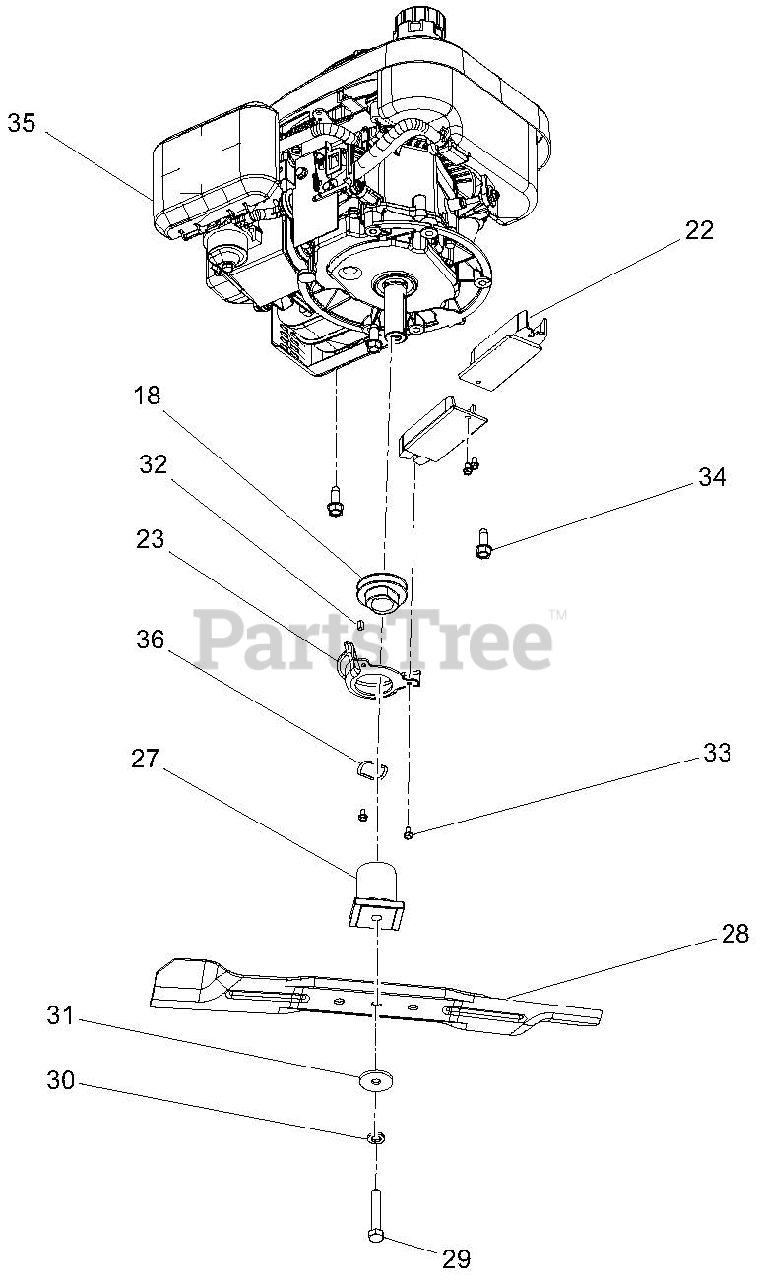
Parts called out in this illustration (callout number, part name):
18	PULLEY, GROUND DRIVE, LM
22	GUIDE, BELT INNER
23	GUIDE, BELT CRANK
27	ADAPTER, BLADE
28	BLADE, MOWER 21" HIGH LIFT
29	@BLT-HEX .4375-20X2.25 GR8 YWZ
30	@WSHR-LK .44X.109 REG YWZC
31	WSHR-FL-STL .4375X1.50X.125 YZ
32	KEY-SQ .188X.188X.625
33	SCR-TAP 10-24X.375 PRE-COAT 80
34	@SCR-TAP .38-16X1.00 HWH TR YZ
35	ENGINE,SERVICE,AC SERIES
35	ENGINE,SERVICE,AC SERIES,ELEC
36	WASHER - WAVE 1.09X1.37X.016
